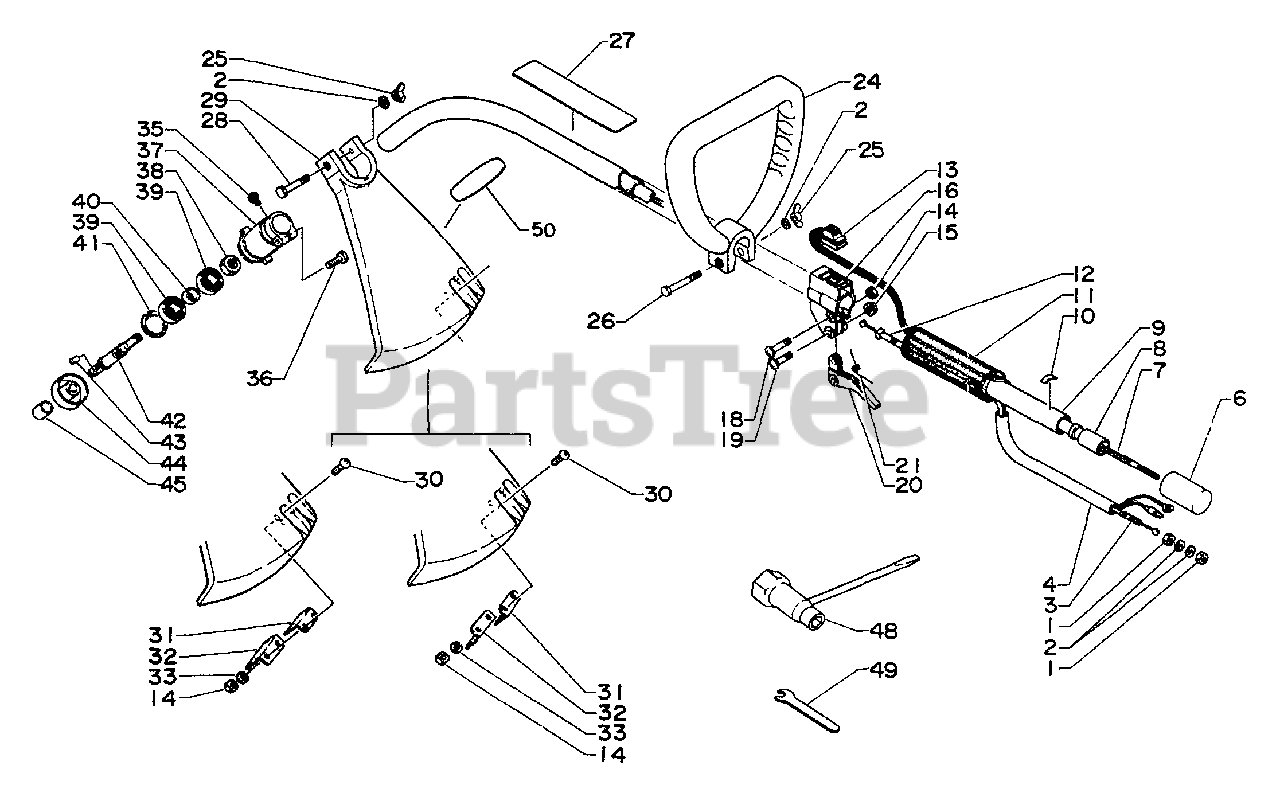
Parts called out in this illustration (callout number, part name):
2	WASHER 6.5×11.5×0.8
3	CABLE, THROTTLE
4	TUBE
7	DRIVESHAFT - FLEXIBLE
8	BUSHING
9	PIPE, MAIN
10	LABEL - ALIGNMENT
11	GRIP, HANDLE
12	GUIDE, CABLE
13	IGNITION SWITCH ASSY
14	NUT M5
15	LOCKNUT - 5
16	BRACKET, THROTTLE
18	SCREW 5×28
20	TRIGGER, THROTTLE
21	SPRING, THROTTLE
24	HANDLE ASSY
25	NUT, WING 6
26	BOLT - 6×40
27	LABEL - CAUTION
27	SHIELD ASSY
28	BOLT - 6×50
29	SHIELD
30	SCREW 5×14
31	KNIFE, TRIMMER LINE
33	WASHER, SPRING 5
35	SCREW 4×10
36	BOLT - 5×25
37	CASE, GEAR
38	NUT 12 L.H.
39	BEARING, BALL 6001 DDU
41	RING, SNAP 28
42	SHAFT, GEAR
44	PLATE, ADAPTER - UPPER
48	WRENCH
50	LABEL - ECHO
